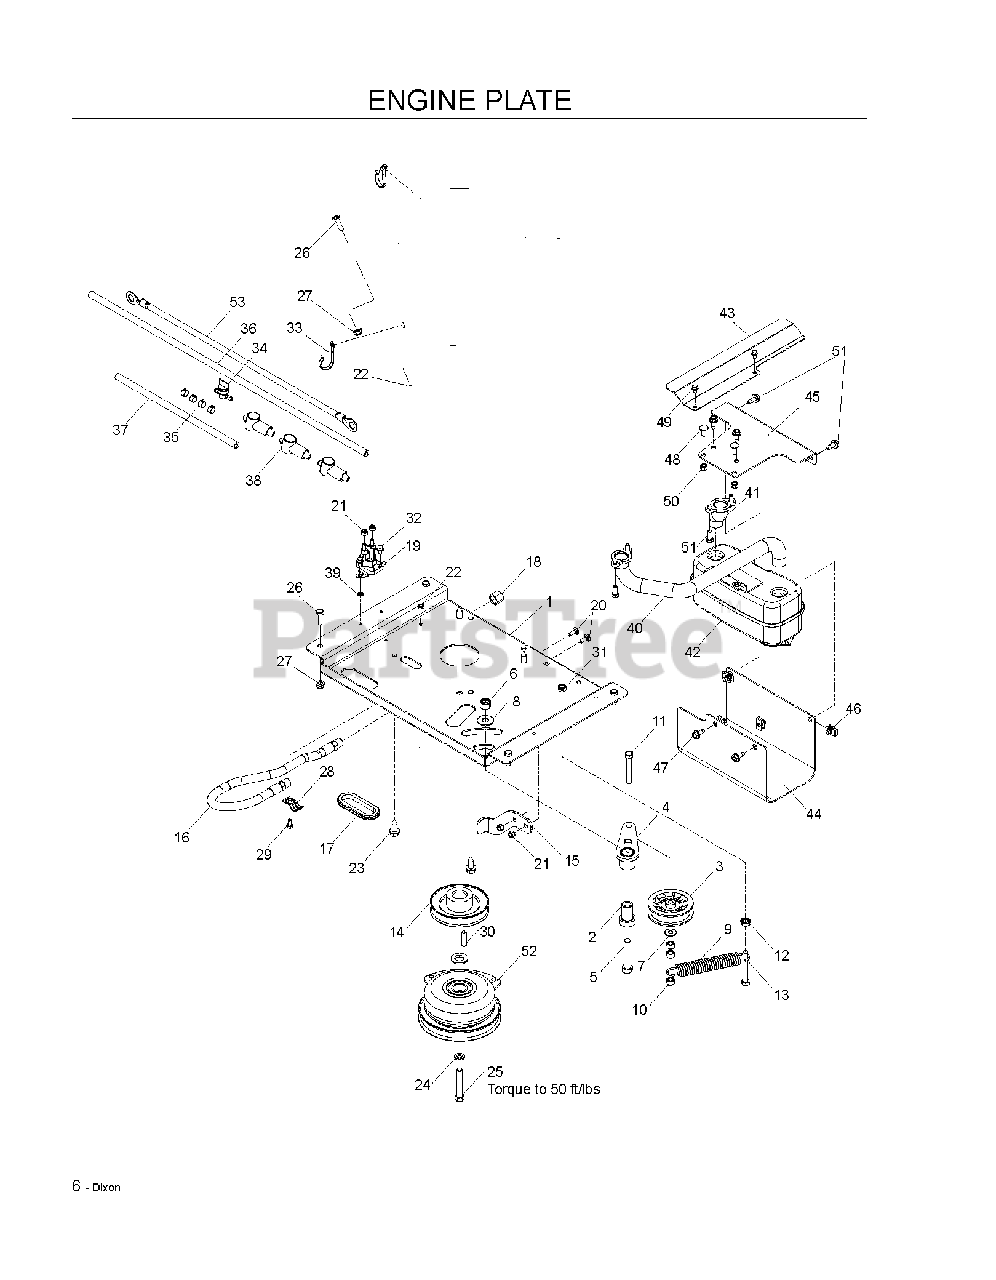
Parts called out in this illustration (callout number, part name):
1	PLATE, ENGINE
2	IDLER SPINDLE
3	PULLEY, IDLER
4	IDLER ARM WELDMENT
5	HEX SCREW 1/2-13 X 2.5" GR 5
6	NUT 1/2-13 HEX NYLOC ZD
7	WASHER 5/16 FLAT
8	WASHER 1/2 FLAT
10	NUT 3/8-16 NYLOC
11	HCS 3/8-16 X 2-1/2 TPBLT
12	NUT 3/8C WHIZ
13	SCREW 3/8C X 2 3/4 HEX CAP
15	TIE DOWN, CLUTCH
16	DRAIN, OIL
17	GROMMET
18	DRAIN CAP
19	SOLENOID
20	RHSNB 1/4C X 3/4
21	NUT 1/4-20 NYLOC
22	JAM NUT 1/4C
23	HHFS 3/8-16 X 1.0 THD FORMING
24	WASHER 7/16 LOCK
25	BOLT 7/16F X 2 1/2
26	HCS 5/16C X 1
27	5/16-18 NYLOC FLANGE NUT
29	HCS 1/4-20.
30	KEY, 1/4 SQ X 1 1/4
31	NUT 3/8C CENTERBLOCK
32	HWST 1/4C X 3/8
34	FUEL VALVE
35	HOSE CLAMP
36	FUEL LINE 30"
37	FUEL LINE 13"
38	INSULATOR
39	WASHER 1/4 INT TOOTH
40	MANIFOLD, FT
41	MANIFOLD, RR
42	MUFFLER ASM TWIN
43	SHIELD, HEAT
44	GUARD, MUFFLER
45	MOUNT MUFFLER BLACK
46	U-CLIP 5/16-18 NUT RETAINER
47	BOLT 5/16-18 X 3/4
48	BOLT 5/16C X 3/4" CARRIAGE
49	HWST 1/4C X 3/8
50	NUT 5/16 NYLOC
51	HCS 5/16C X 3/4
52	CLUTCH, 200 FT/LB
53	CABLE, POSITIVE
